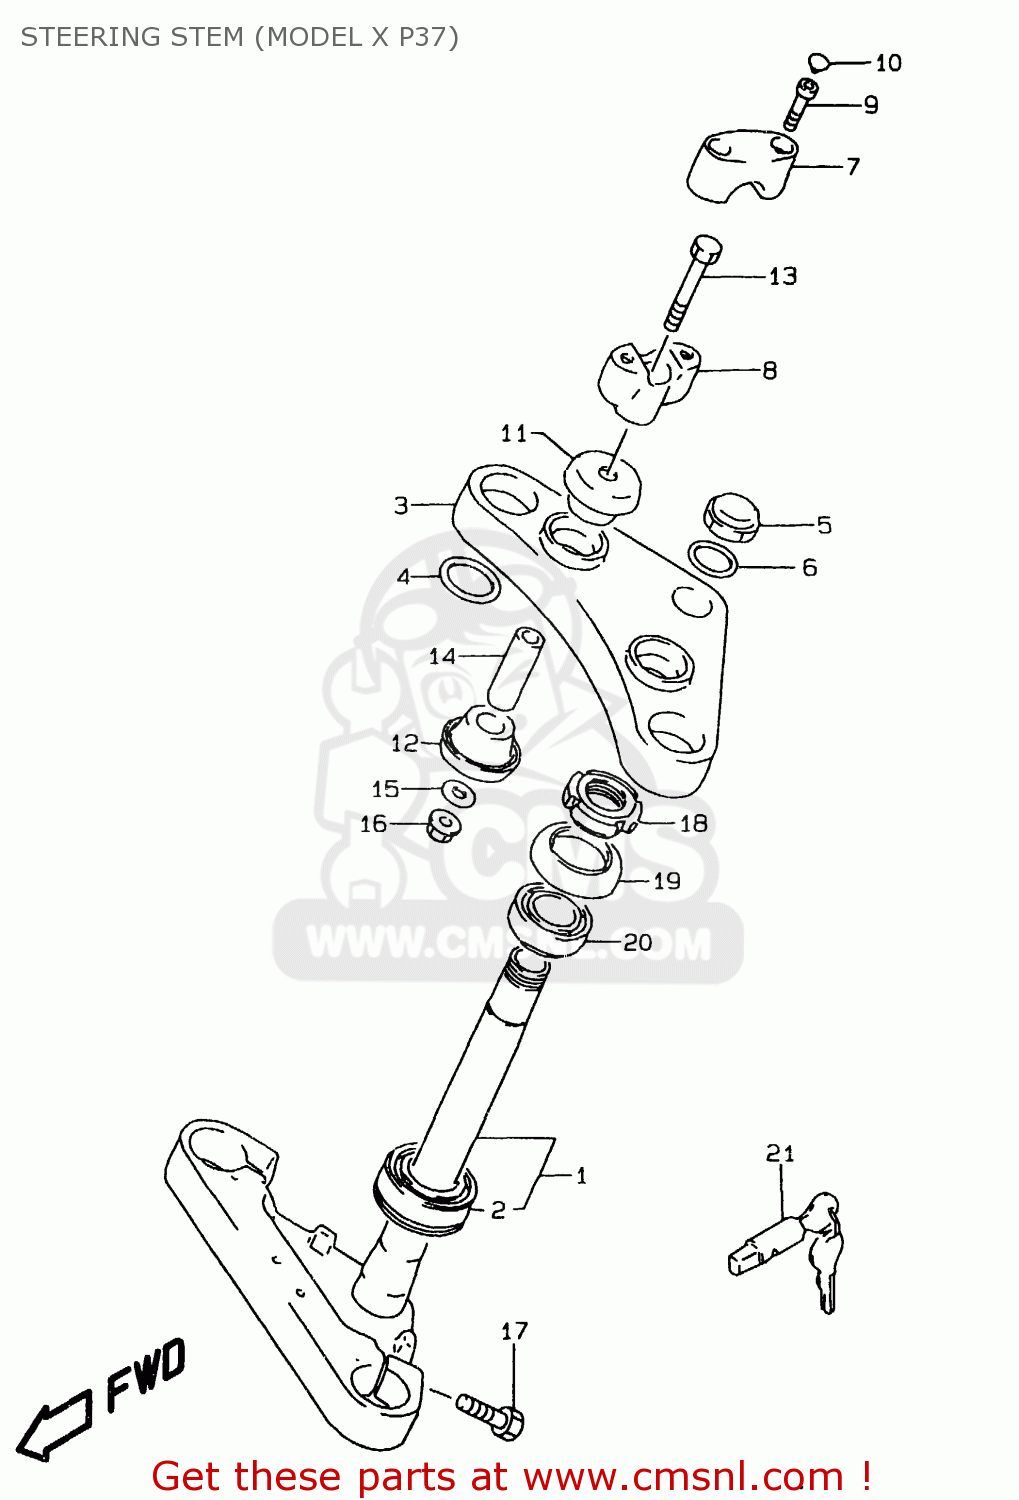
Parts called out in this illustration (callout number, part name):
1	STEM, STEERING
2	BEARING(30X55X17)
3	HEAD, STEERING STEM
4	WASHER,STEM HEAD,LOWER
5	NUT,FRONT FORK,UPPER B
6	WASHER(22.5X32X1.6)
7	HOLDER,HANDLE UPR
8	HOLDER,HANDLE LWR
9	BOLT,HOLDER UPR(07130-08307)
10	CAP(OD:14.5)
11	CUSHION,UPR
12	CUSHION,LWR
13	BOLT,DAMPER(10X77)
14	SPACER,HOLDER LOW(09180-10065)
15	WASHER
16	NUT
17	BOLT
18	NUT,STEERING STEM(25X44X10)
19	SEAL,STEERING UPR DUST
20	BEARING(25X47X15)
21	LOCK ASSEMBLY,STEERING (NEI
